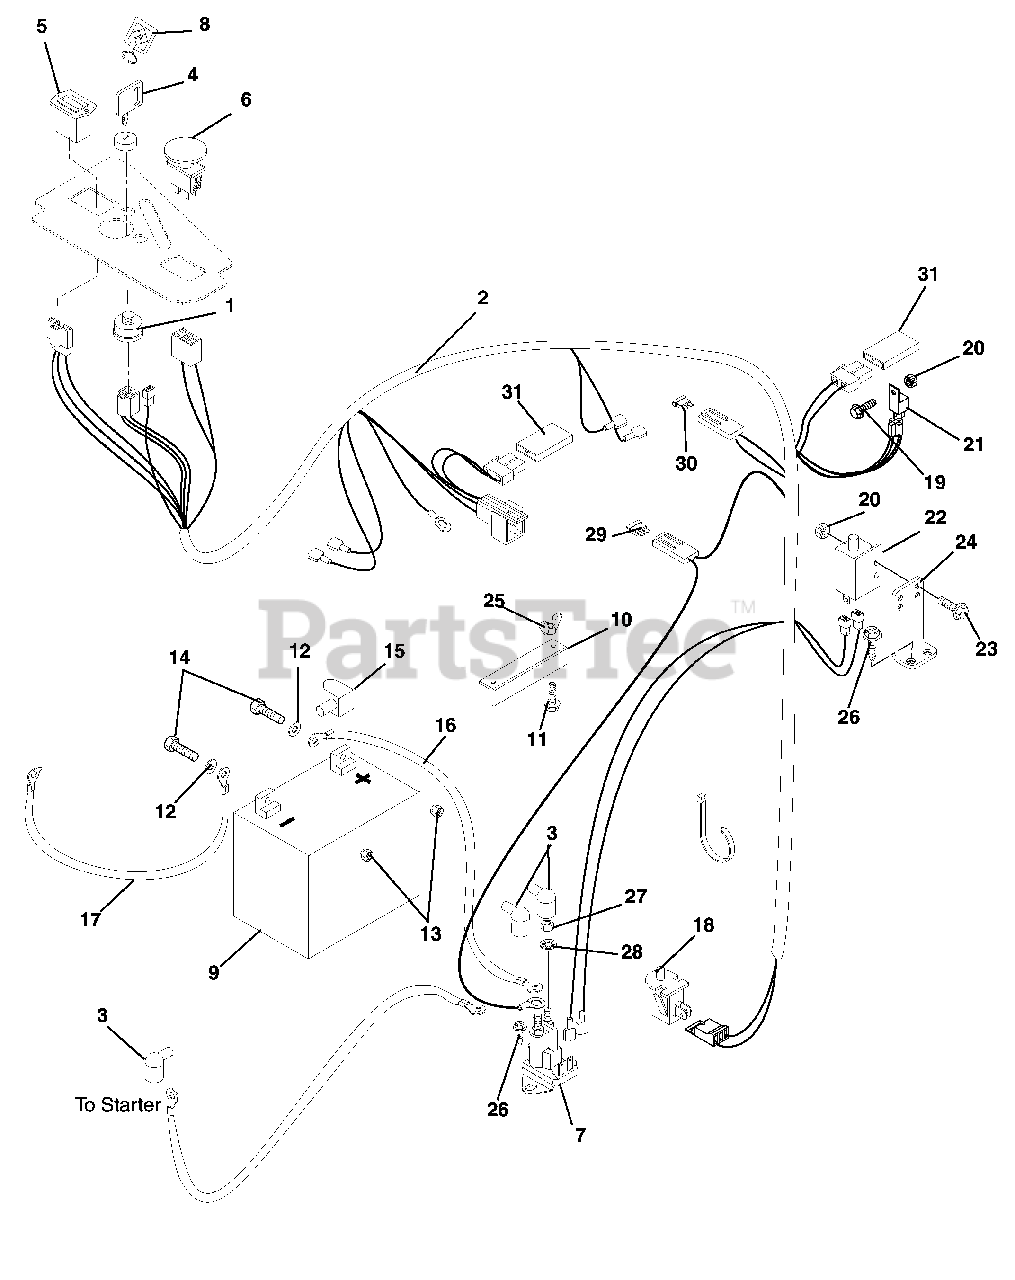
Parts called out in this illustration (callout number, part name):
1	Key Switch
2	Harness, Z 6-Pin Wiring
3	Boot, Eyelet Terminal
4	Key with Shield
5	Hour Meter
6	Switch, Clutch With Retainer Ring
7	Solenoid
8	Key Chain
10	Hold Down
11	Bolt, Round Head Square Neck .25-20 x 7.50
12	Washer, Flat Steel .281 x .620 x .065
13	Nut, Locking Top Flange .25-20
14	Bolt, Hex .25-20 x .75 Grade 5
15	Insulator
16	Cable, Positive Battery 9.00"
17	Ground Cable
18	Switch, Snap Mounting (N.O.)
19	Screw, Machine 10-24 x .50 Hex Washer Head
20	Nut, Locking Nylon 10-24 With Insert
21	Relay
22	Switch, Single Pole
23	Screw, Machine 10-24 x .75 Hex Washer Head
24	Mount, Brake Switch
25	Nut, Locking Wing .25-20
26	Screw, Tapping .25-20 x .50 Hex Washer Head
27	Nut, Jam .31-24
28	Washer, Locking .31 x .078 Regular
29	Fuse, 25 Amp
30	Fuse, 20 Amp
31	Diode, Connector Shell
